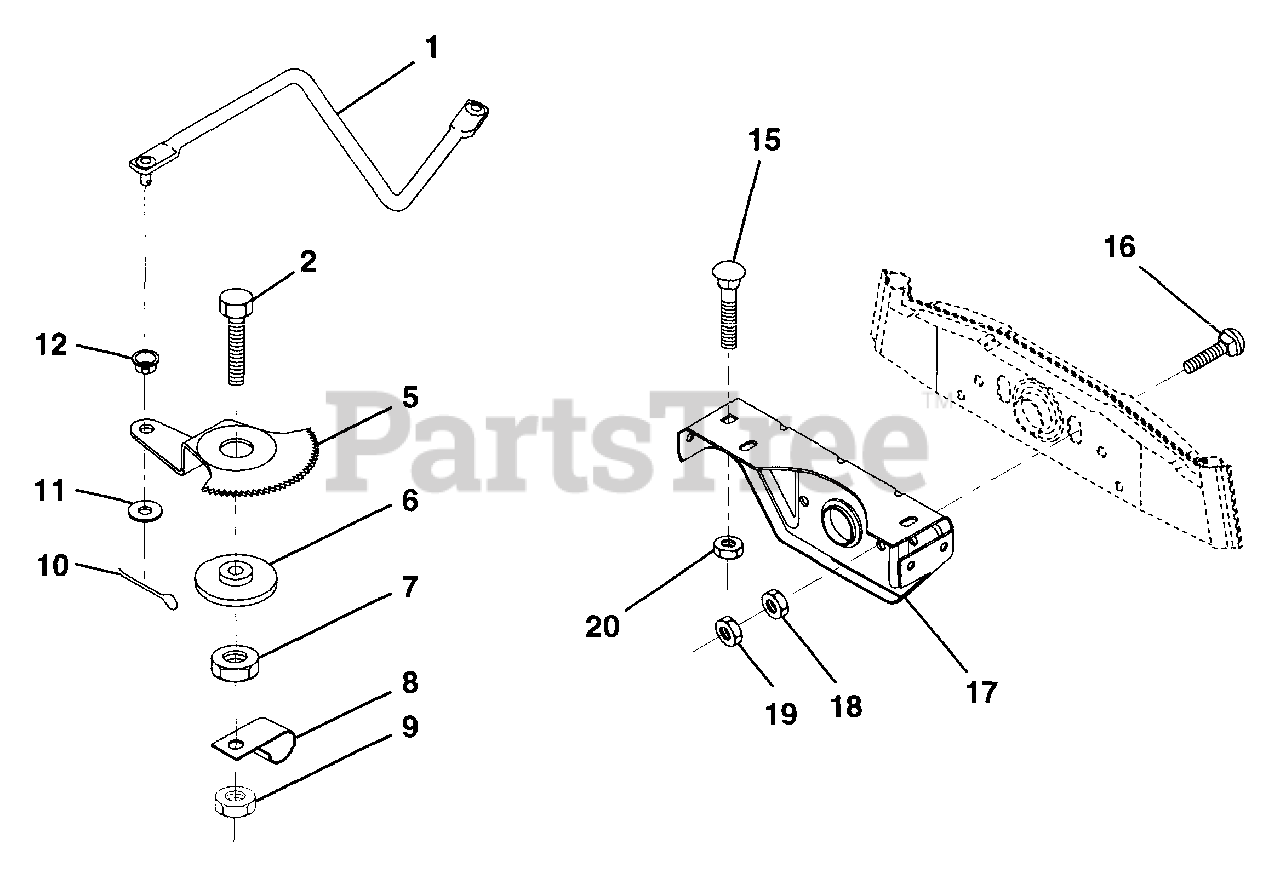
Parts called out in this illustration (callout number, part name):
1	Link, Drag
2	Bolt, Hex, Fin. 1/2-13 x 1-3/4
5	Gear, Sector
7	Nut, Heavy Hex, Top Lock 1/2-13 UNC
8	Clip, Insulated
9	Nut, Crownlock 3/8-16
10	Pin, Cotter 1/8 x 3/4
11	Washer 13/32 x 13/16 x 16 Ga.
15	Bolt, Carriage 3/8-16 UNC x 3/4
16	Bolt, Carriage
17	Support, Front Axle
18	Nut, Hex, Fin. 3/8-16 UNC
19	Nut, Centerlock 3/8-16 UNC
20	Nut. Crownlock 3/8-16 UNC
